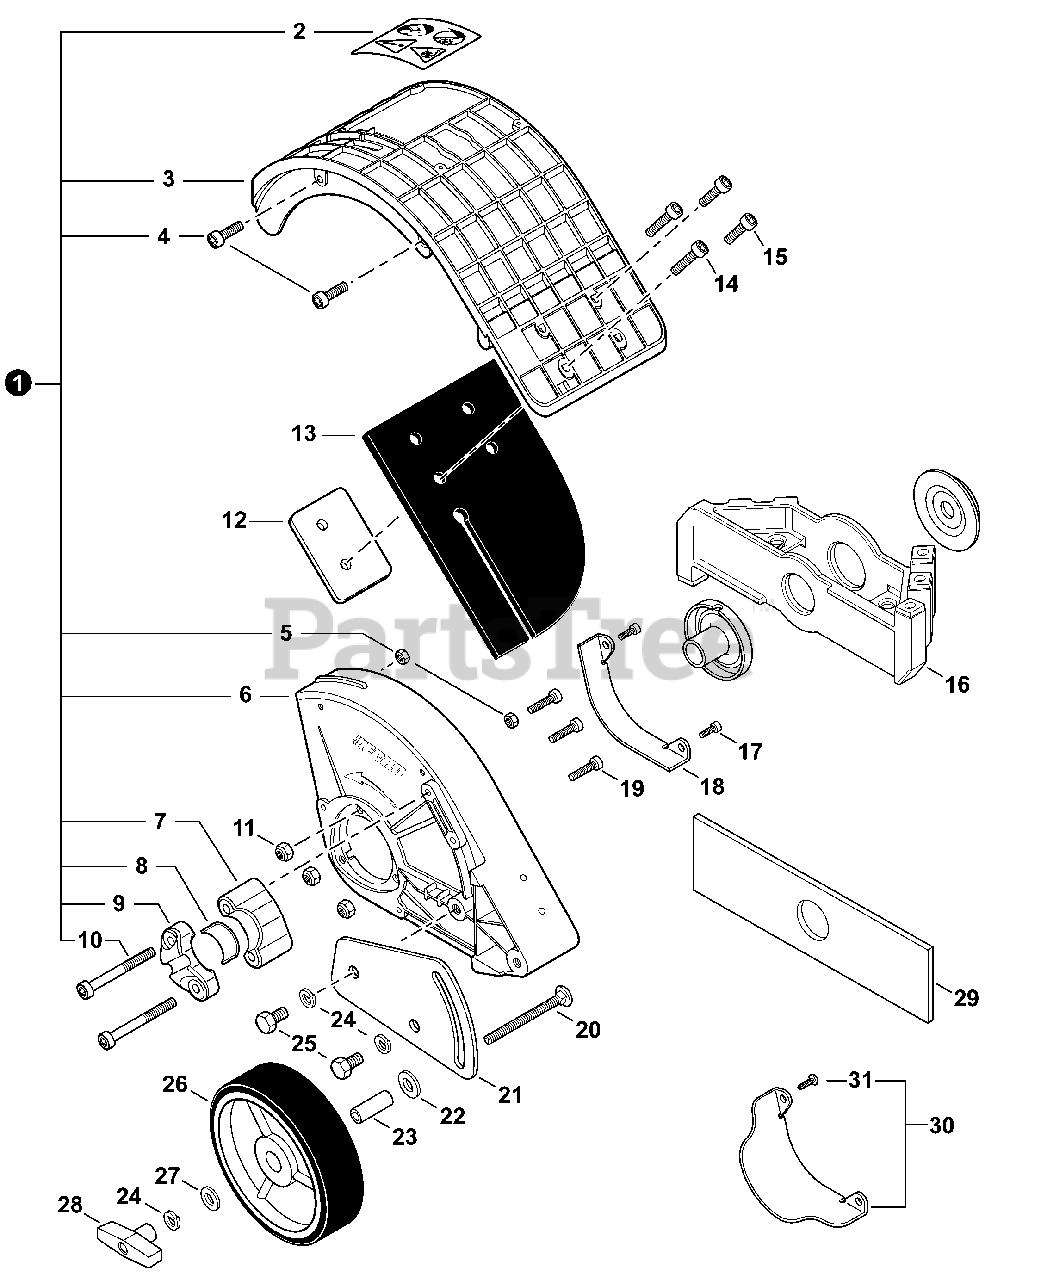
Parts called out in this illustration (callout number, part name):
1	BED REDEFINER KIT
2	LABEL, CAUTION
3	SHIELD, DEBRIS
4	BOLT, TORX 4×12
5	NUT, LOCK 4
6	SHIELD, BLADE
7	BRACKET - INNER
8	PAD, FOAM
9	BRACKET - OUTER
10	SCREW - 6×35
11	NUT, LOCK M5
12	PLATE, FLAP
13	FLAP, DEBRIS
14	BOLT, TORX 4×16
15	BOLT, TORX 4×12
16	BLADE, REDEFINER
17	BOLT, TORX 4×12
18	GUARD, SHIELD
19	BOLT, TORX 5×20
20	BOLT 5/16"-18×2-1/2"
21	BRACKET, WHEEL
22	WASHER, SPRING 10
23	COLLAR 12
24	WASHER, SPRING 8
25	BOLT 8×14
26	WHEEL
28	KNOB, FASTENER
29	BLADE - 2 PK
30	GUARD KIT, SHIELD
31	SCREW 4×12
